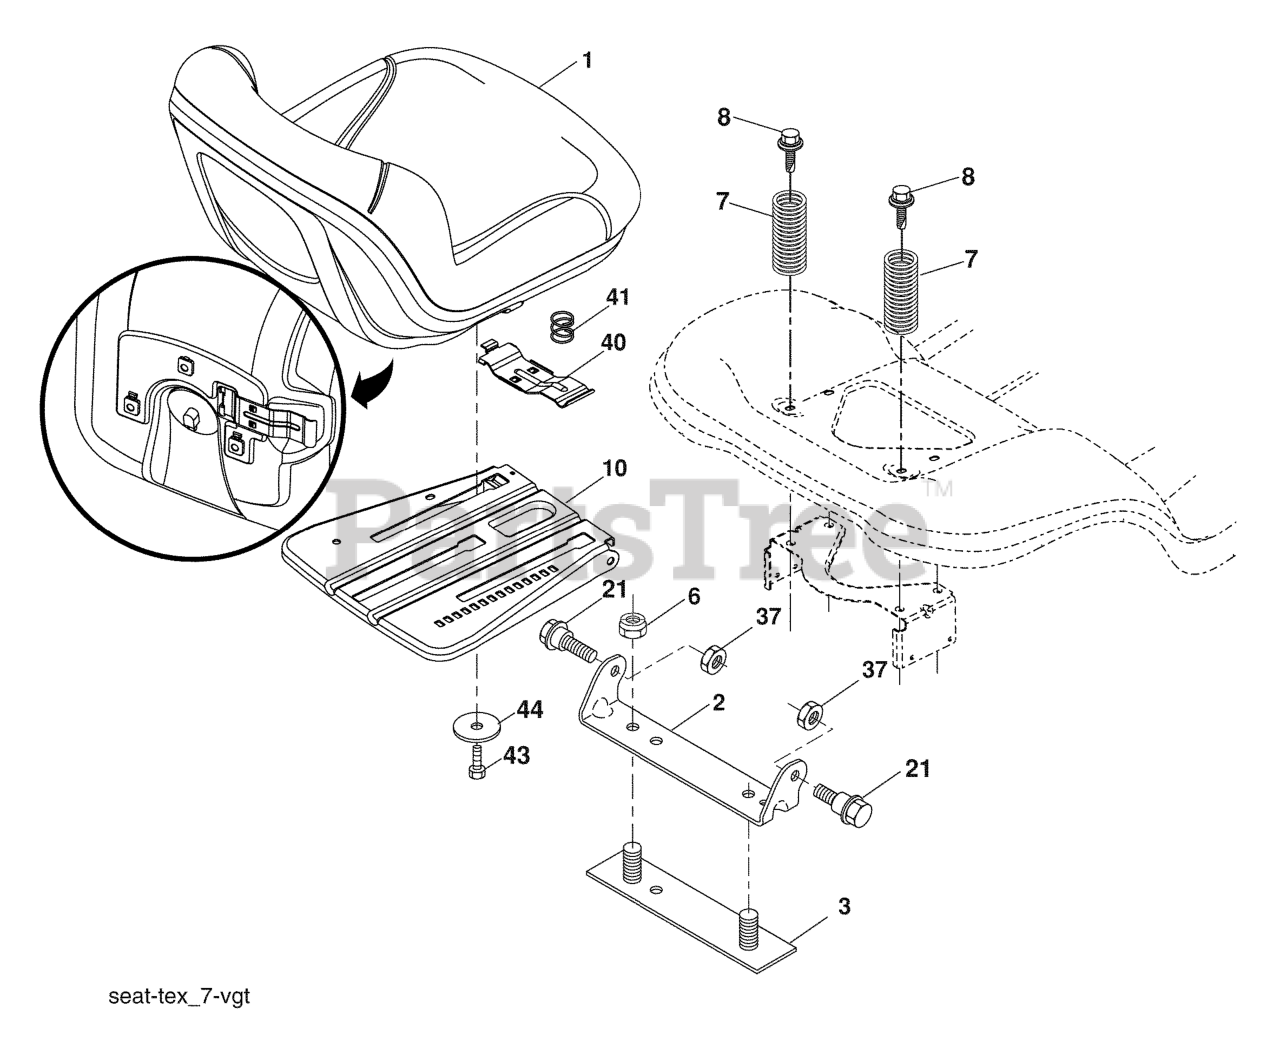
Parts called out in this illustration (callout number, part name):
1	SEAT - GREY
2	BRKT.PIVOT.FENDER
3	STRAP
6	NUT
7	SPRING COMPRESSION
8	BOLT.5/16-18UNCX3/4 W/SEMS.BLK
10	PAN.ASM.SEAT.3PT
21	BOLT.SHOULDER.5/16-18
37	NUT.71038.31-18.HEX.NYLOCK
40	HANDLE.SLIDE.SEAT.TEX.BLACK
41	SPRING.LATCH.SEAT.TEX
44	WASHER 13/32 X 2-3/8 X 12GA
